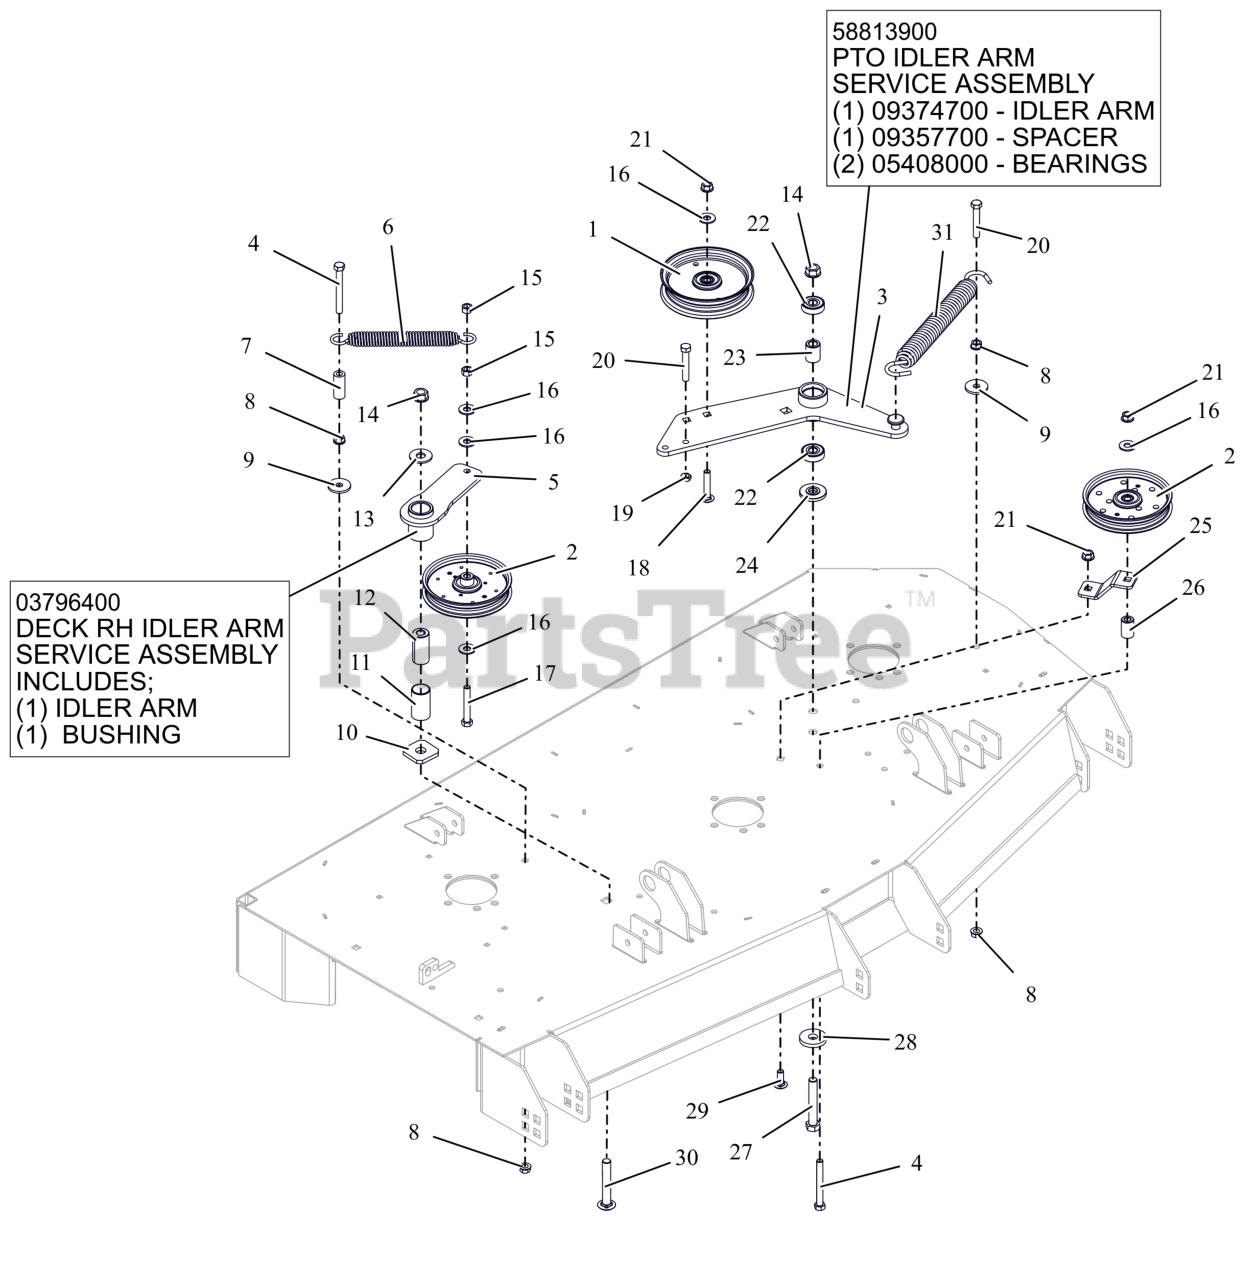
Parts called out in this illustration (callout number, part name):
1	IDLER- FLAT - 5.00" X .75"
2	IDLER- 5" FLANGED
3	WLDMT, IDLER ARM PT660
3	PTO IDLER ARM
3	SPACER .510 X .867 X 1.1485
3	BRG-BALL .500X1.38X.437
4	BLT, HEX .38-16X3.25 G5 ZCC
5	WMT, IDLER ARM - BLACK
5	ASM, IDLER ARM (DECK)
5	BSHG, 1.00X1.125X1.937
6	SPRING- EXTENSION
7	HOSE, .38 X 1.65
8	NUT, SPNLK-FLG .38-16 G5 ZCC
9	WSHR,FLT .406X1.375X.135 ZCC
10	WSHR-FLT .640X1.75X.250
11	BSHG, 1.00X1.125X1.937
12	BSHG, SPCR .502X.997X2.03 PM
13	WSHR,FLT .563X1.375X.109 ZCC
14	NUT-LK-CTR-FLG .500-13 GG ZCC
15	NUT-LK-CTR .38-16 ZC120
16	WSHR,FLT .438X1.00X.083 ZCC
17	BLT, HEX .38-16X2.50 G5 ZCC
18	BLT,RHSSN.375-16X2.00 G5 ZCC
19	NUT-JAM .375-16 G2 ZCC
20	BLT,HEX .38-16X2.25 G5 ZCC
21	NUT-LK-CTR-FLG .375-16 GF ZCC
22	BRG-BALL .500X1.38X.437
23	SPACER .510 X .867 X 1.1485
24	SPACER, IDLER ARM
25	PTO FIXED IDLER MTG BRKT -RED
26	BUSHING, SLV .380X.750X1.190
27	BLT,HEX .50-13X3.25 G5 ZCC
28	WSHR-FL-STL 0.557X1.625X0.25 ZCC
29	BLT,RHSSN .38-16X1.00 G5 ZCC
30	BTL,RHSSN .500-13 X 3.25 G5 ZCC
31	SPRING, EXTENSION
